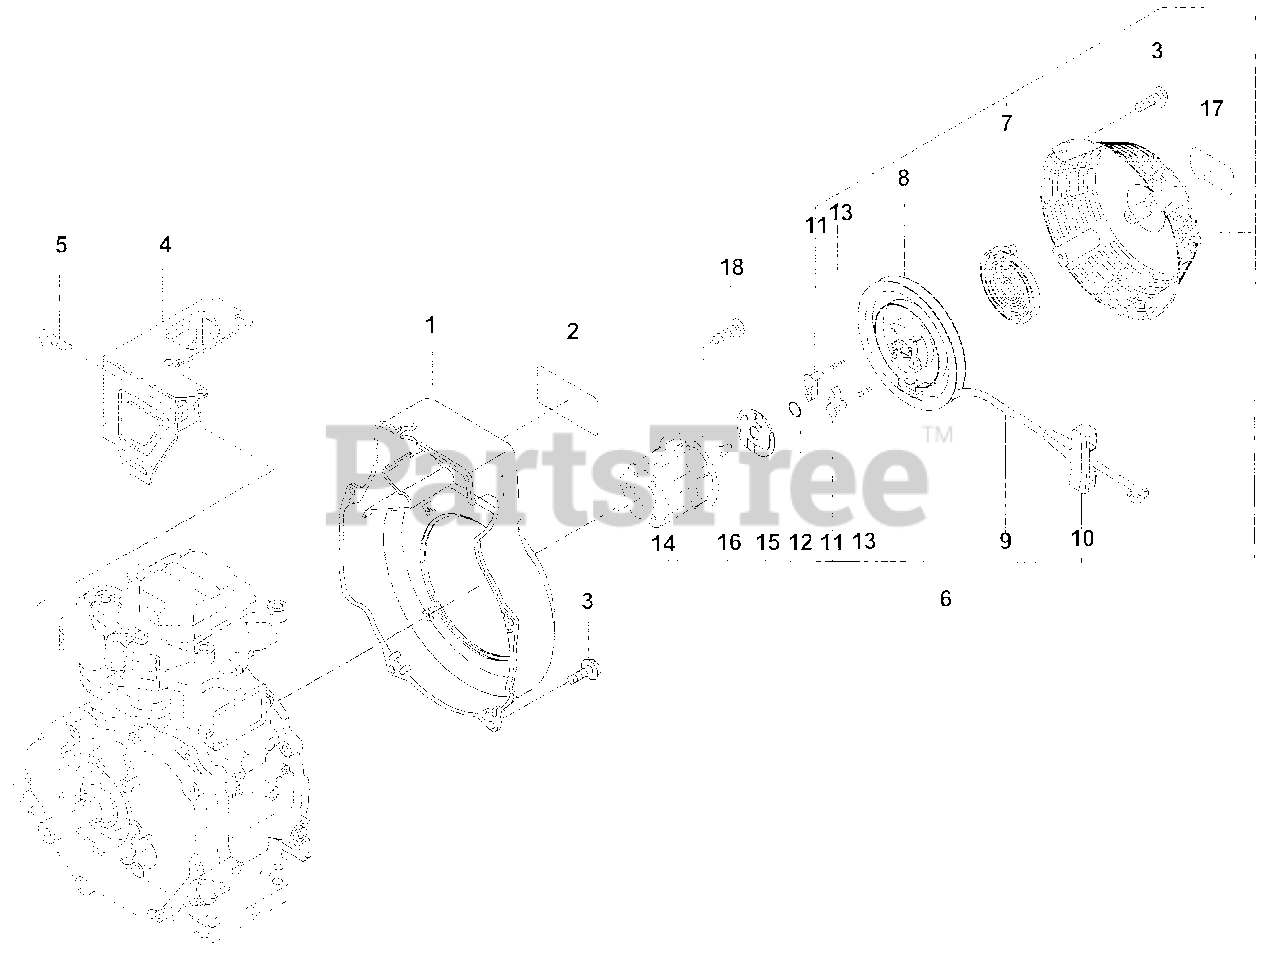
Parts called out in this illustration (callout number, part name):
1	Blower housing
2	Label (trademark)
3	Flange bolt
4	Cylinder Baffle cp
5	Flange bolt
6	Recoil starter assy
7	Spring rewind
8	Reel
9	Starter rope
10	Starter knob
11	Ratchet
12	Friction spring
13	Return spring
14	Pulley
15	Ratchet guide
16	Set screw
17	Label, OHV
18	Bolt
